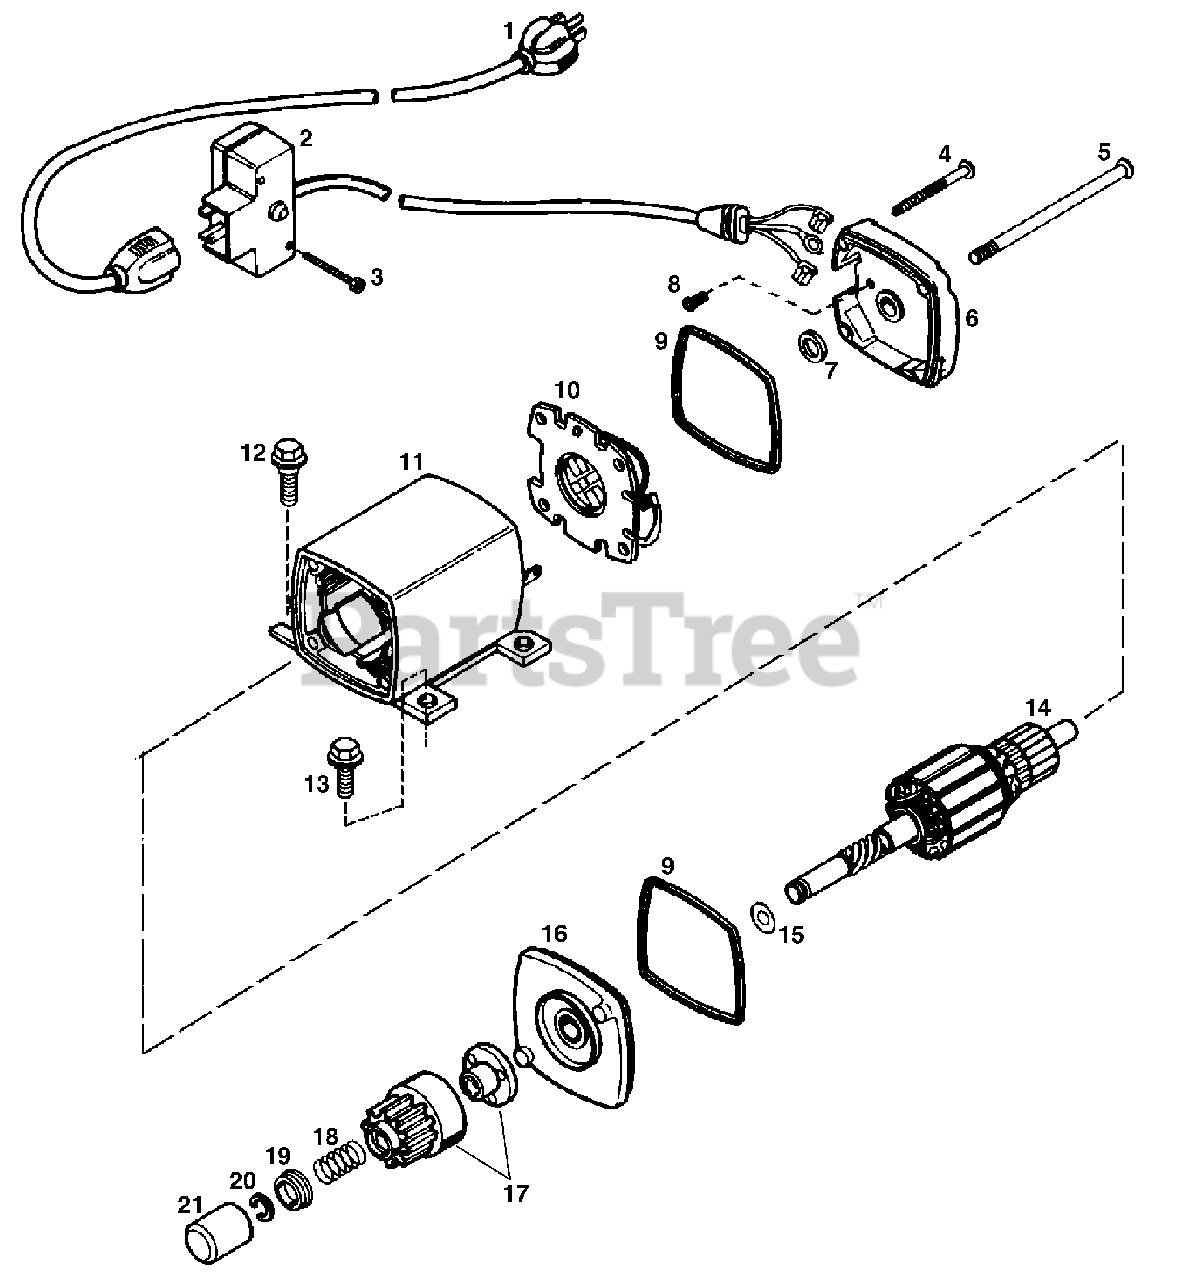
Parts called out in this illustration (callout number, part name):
1	Extension Cord (10'6")
2	Switch Box Ass’y.
3	Screw, 12-16 x 5/8"
4	Ground Screw
5	Case Bolt
6	Commutator End Cap Ass’y
7	Thrust Washer
8	Ground Screw
10	Brush Card Ass’y
11	Housing Ass’y
12	Screw, 1/4-20 X 1/2"
13	Screw, Torx T-30, 1/4-20 X 1/2"
15	Thrust Washer
16	Drive End Cap Ass’y.
17	Gear & Nut
18	Anti-drift Spring
19	Spring Retainer
20	Retainer Ring
21	Dust Cover
